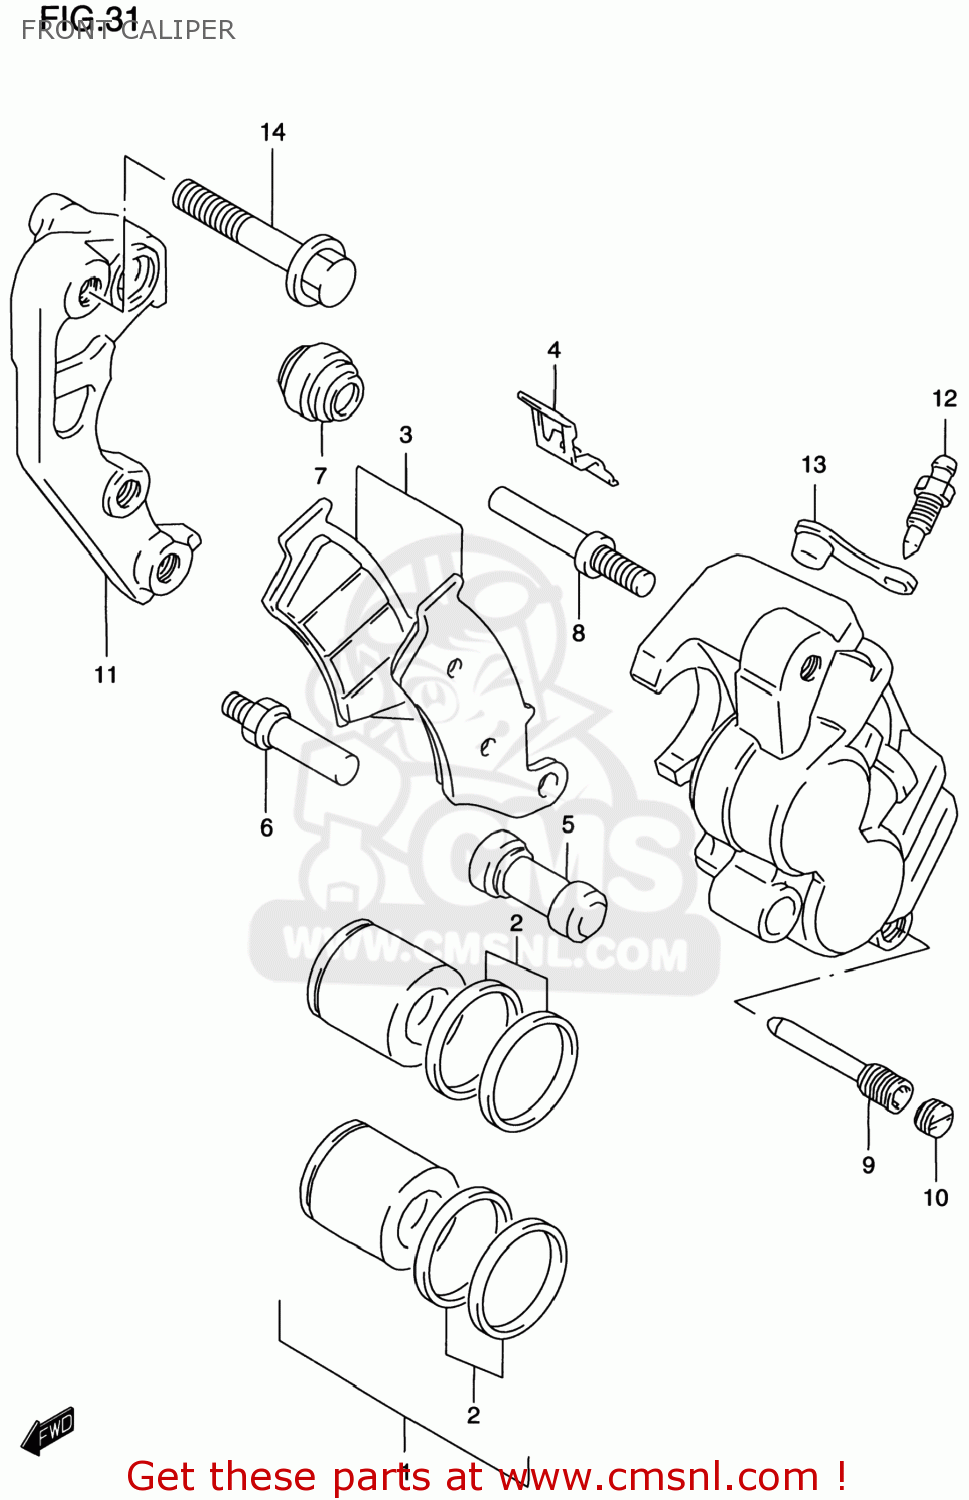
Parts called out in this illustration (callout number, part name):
1	PISTON SET
2	SEAL SET,PISTON
3	PAD SET (NAS)
4	SPRING,PAD
5	BOOT
6	BOLT
7	BOOT
8	PIN
9	PIN,HANGER
10	PLUG,PIN
11	BRACKET
12	BLEEDER
13	CAP,BLEEDER
14	BOLT(8X40)
